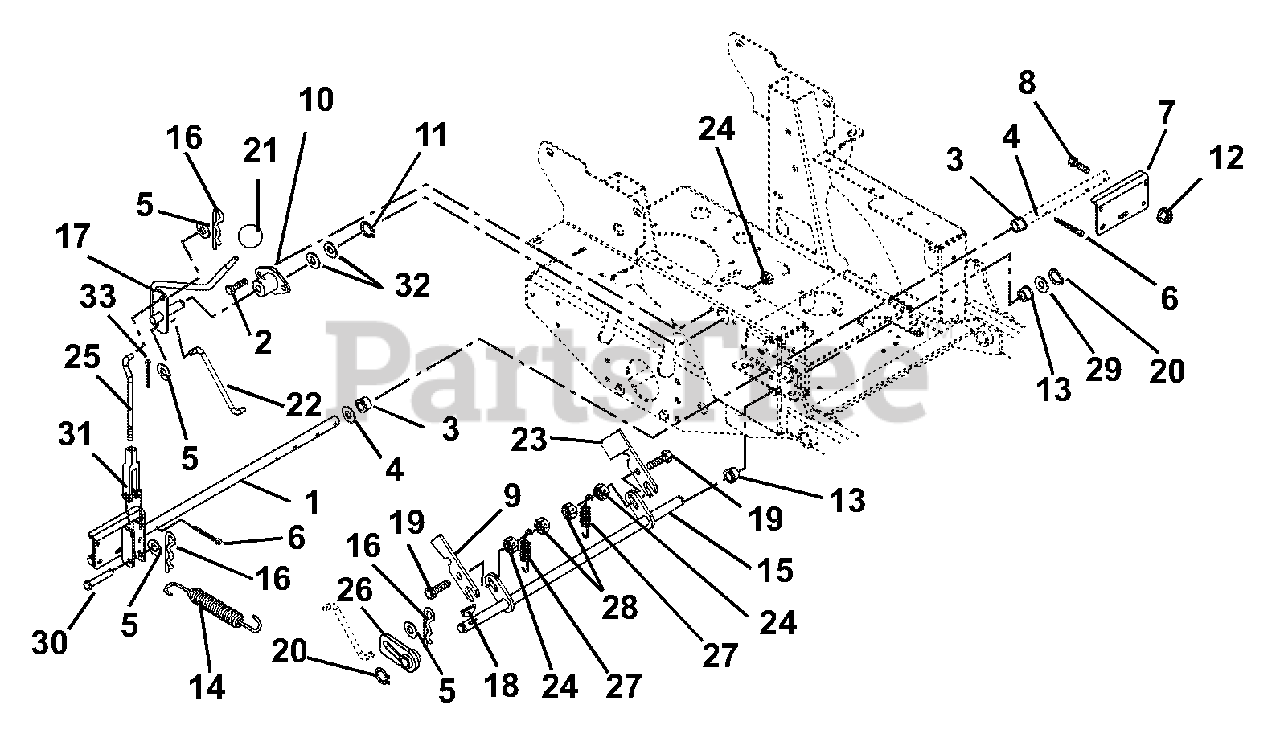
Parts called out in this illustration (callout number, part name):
1	WMT, BRAKE SHAFT
2	@BLT-HEX .31-18X.75 GR5 YWZC
3	BSHG-FLG .762X1.0X.580X1.48 NY
4	WSHR-FL-STL.755X1.375X.062YWZC
5	@WSHR-FL-STL.406X.812X.065 YWZ
6	@PIN-CTR .12X1.00 EXTPRSQCT YZ
7	WMT, PADDLE BRAKE
8	@BLT-HEX .25-20X1.25 GR5 YWZC
9	SLIDE, INTERLOCKING BRAKE
10	BUSHING, FLANGED
11	RG-RTNG-EXT .625X.050
12	@NUT-LK-TOP-FLG .25-20 YWZC
13	BSHG-FLG.500X.750X.750X1.000BR
14	SPRING - ENGINE - TRANS.
15	WMT, MECHANICAL BRAKE
16	PIN-HAIR, ENDRIES #25 YWZC
17	WMT, BRAKE ACTUATING
18	KEY-WDRF .13X.63 HRD#5
19	@BLT-HEX .31-18X1.25 GR5 YWZC
20	RG-RTNG-EXT .500X.050 (SNAP)
21	KNOB-STEERING LOCK
22	LINKAGE, BRAKE ACTUATING
23	INTERLOCK, SAFETY SWITCH
24	@NUT-LK-TOP-FLG .31-18 YWZC
25	LINKAGE, BRAKE COMPACT-Z
26	WMT, PARKING BRAKE HUB
27	SG-TENS .061 X .50 X 3.0 WLD 4
28	@NUT-LK-CTR .31-18 YWZC
29	WSHR-FL-STL .505X1.00X.062YWZC
30	PIN-CLEV .370X1.75
31	CLEVIS, .38-24 ADJ.
32	WSHR-FL-STL .630X1.250X.062 YZ
33	@PIN-CTR .09X.75 EXTPRSQCT YWZ
